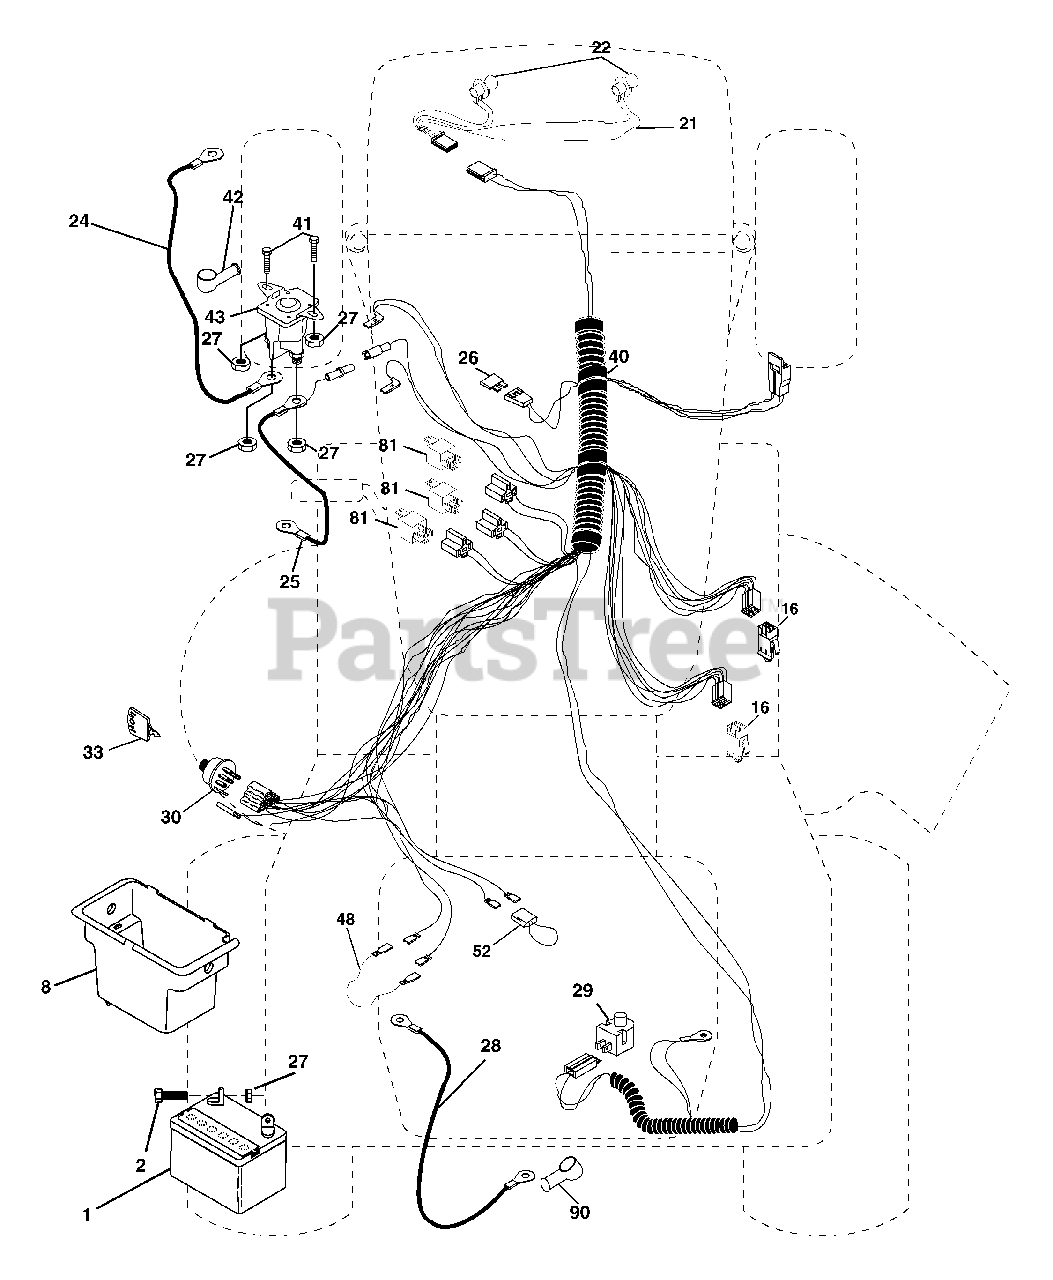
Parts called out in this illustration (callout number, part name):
1	Battery 12 Volt 28 AMP
2	Bolt Hex Hd 1/4-20unc X 3/4
8	Battery Box
16	Switch Interlock Push-In
21	Harness Asm Light W/4152j
22	Bulb Light #1156
24	Cable Battery 6 Ga 11" red
25	Cable Battery 6 Ga 44" red w/16 wire
26	Fuse 20 AMP
27	Nut Keps Hex 1/4-20 Unc
28	Cable Ground 6 Ga 12" black
29	Switch Plunger
30	Switch Ign
40	Harness Ign.
41	Bolt Blk Fin Hex 1/4 - 20 x 1/2
42	Cover Terminal Red
43	Solenoid
48	Adapter Ammeter
52	Protection Wire Loop
81	Relay Asm.
90	Cover Terminal
